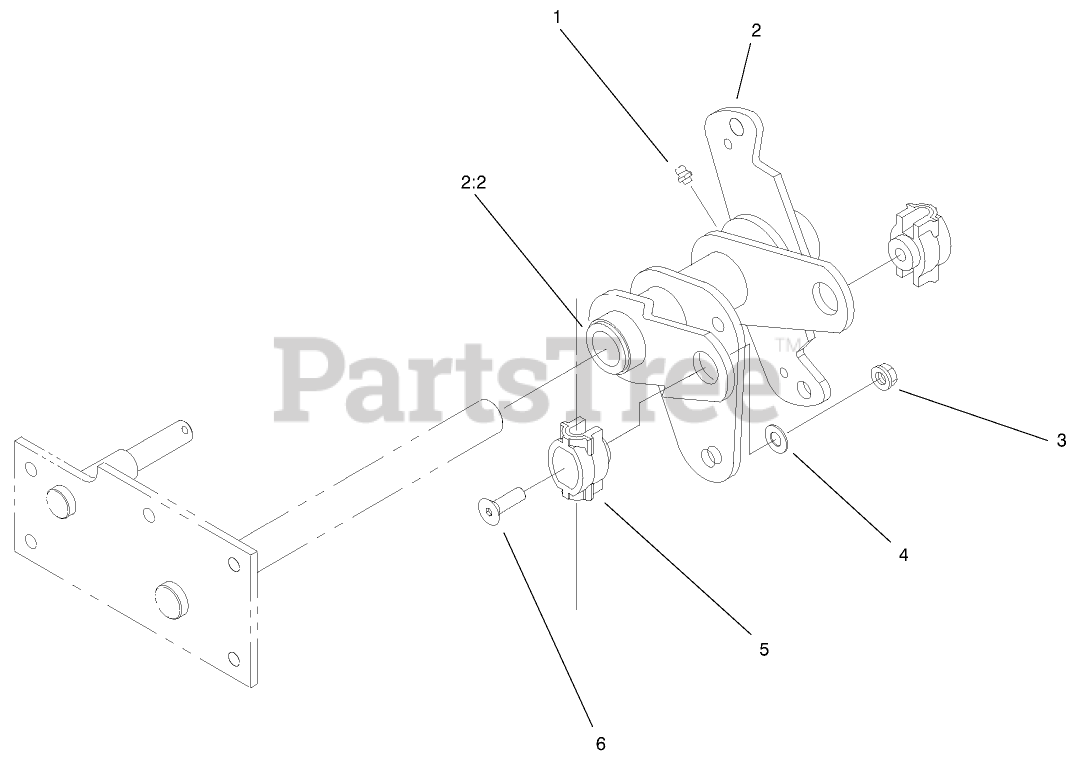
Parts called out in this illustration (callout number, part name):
1	FITTING-GREASE
2	BELLCRANK AND BUSHING ASM
2:2	BUSHING-FLANGED
3	NUT-LOCK, NI
4	WASHER-FLAT
5	SLEEVE-LIFT
6	SCREW-HSFH
